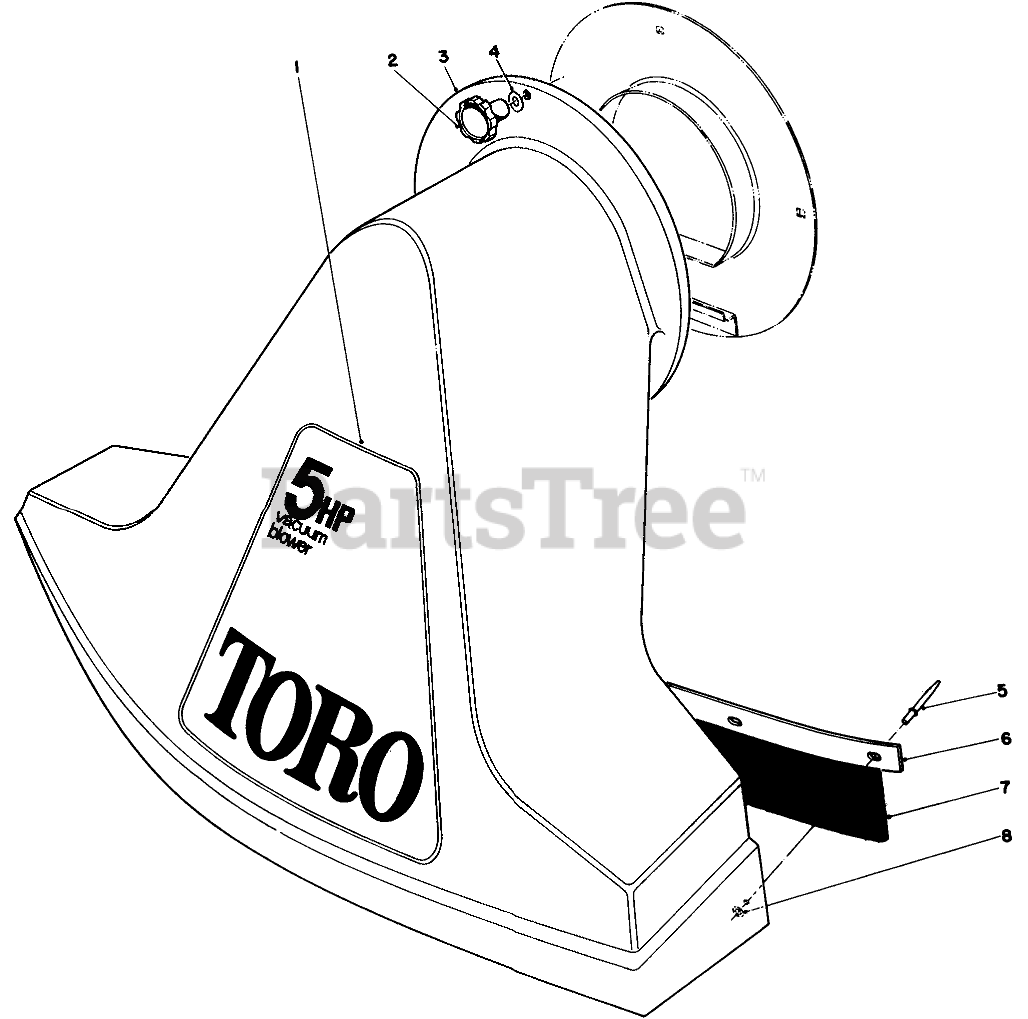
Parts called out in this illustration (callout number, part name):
1	Decal-Toro Model No. 62912
3	Snout Assembly (Incl. Ref. #5-8)
4	Washer
5	POP RIVET 3/16X.375LG
6	Clamp-Flap
7	FLAP-RUBBER
8	WASHER-FLAT
